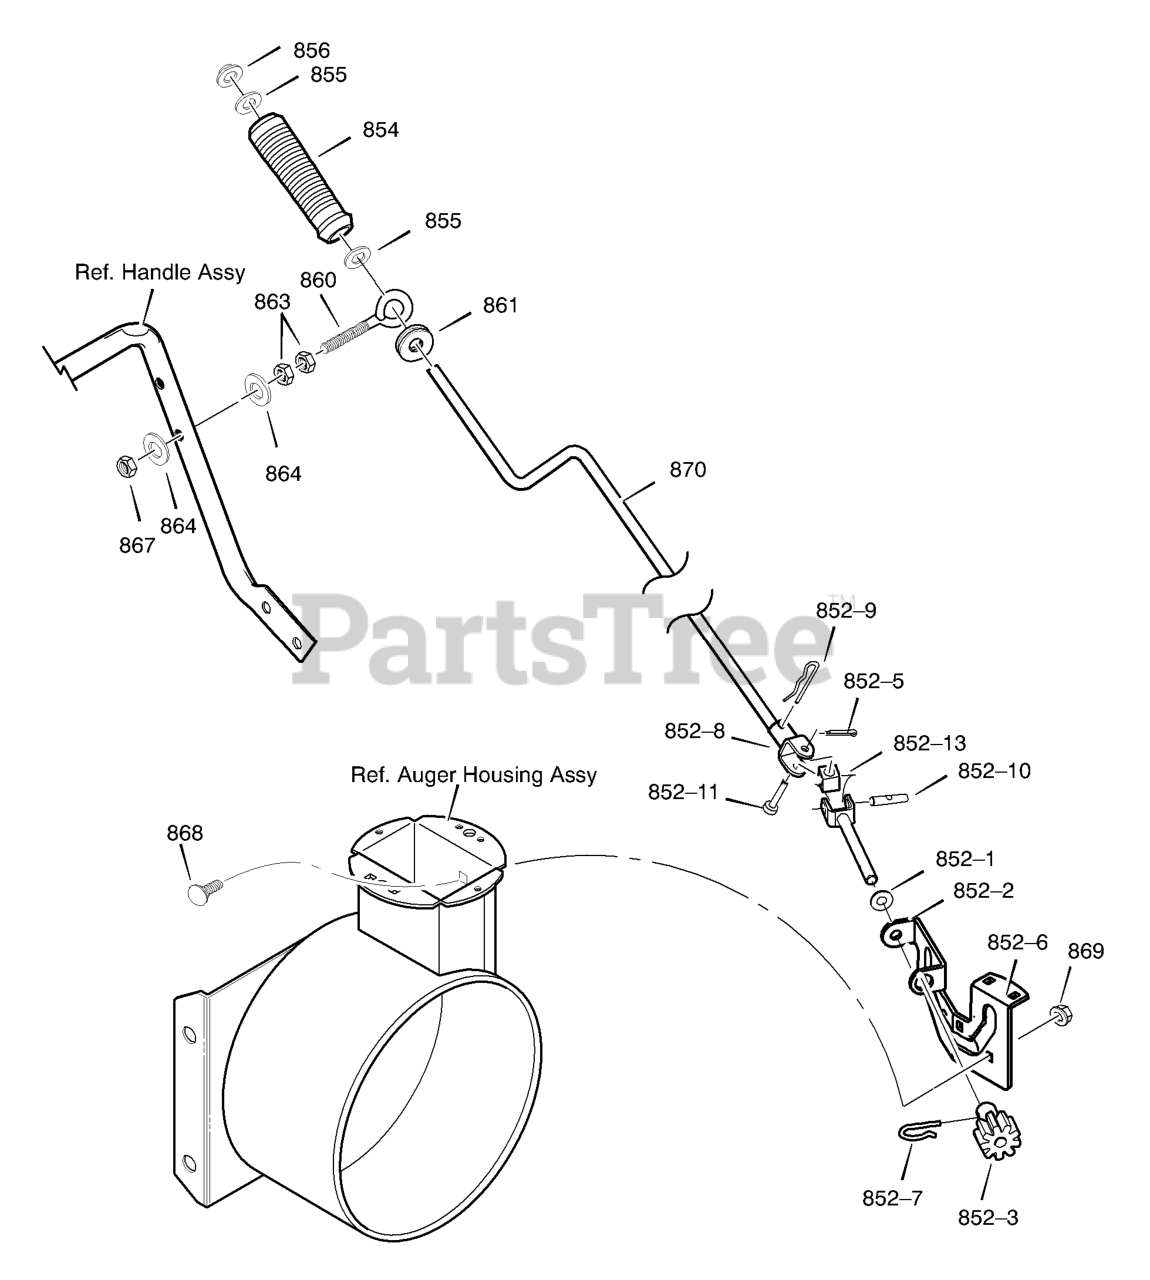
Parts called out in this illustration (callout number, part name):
852-1	ASSEMBLY, YOKE & ROD
852-2	WASHER, CURVED SPRING
852-3	GEAR, CHUTE ROTATION 9T
852-5	PIN, COTTER
852-6	BRACKET, GEAR MOUNT
852-7	PIN, HAIR
852-8	ASSEMBLY, YOKE ADAPTER YZ
852-9	PIN, HAIR
852-10	PIN, UNIVERSAL JOINT
852-11	PIN, CLEVIS
852-13	HOUSING, UNIVERSAL
854	KNOB, SLEEVE
855	FLATWASHER
856	NUT, PUSH ON 3/8"
860	EYE BOLT 3/8-16X6.00
861	GROMMET, EYE BOLT
863	NUT, 3/8-16 HEXJAM
864	FLATWASHER .406X.81X.066
867	NUT, 3/8-16 HEXNYL
868	BOLT, CARRIAGE 1/4-20 X 1.00
869	NUT, HEX 1/4-20 NYLOCK YZ
870	CRANK, ASSY CHUTE
